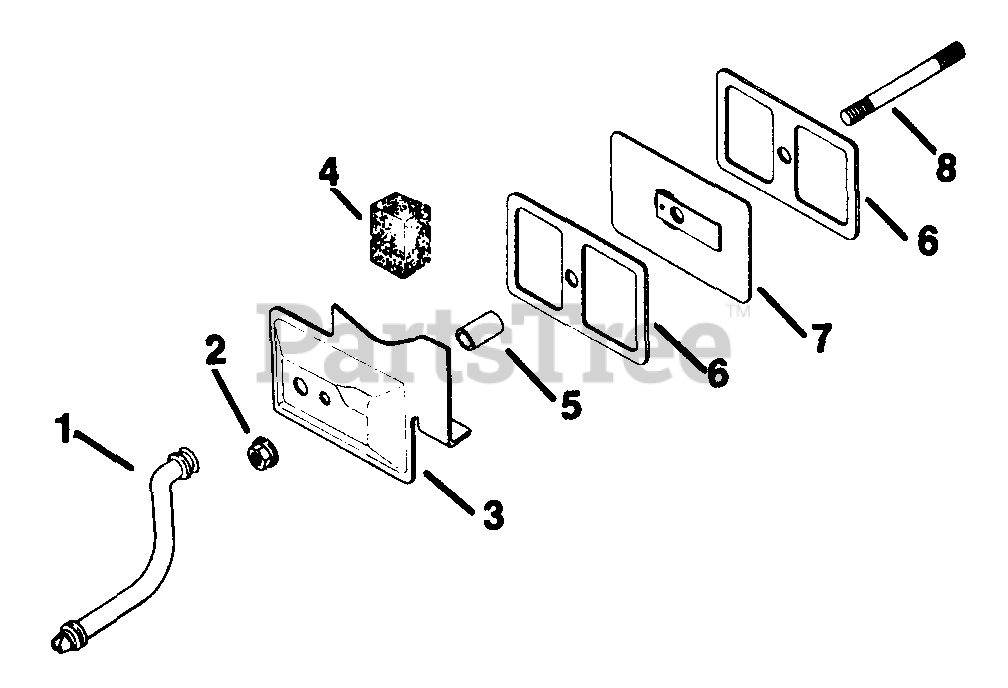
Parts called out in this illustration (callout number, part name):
2	PALNUT, 1/4-20
3	COVER - USE 41 096 26
4	FILTER, BREATHER
5	SEAL, BREATHER
7	BREATHER - DISCONTINUED
8	STUD,1/4-20x3-9/16"-DISCONTINUED
